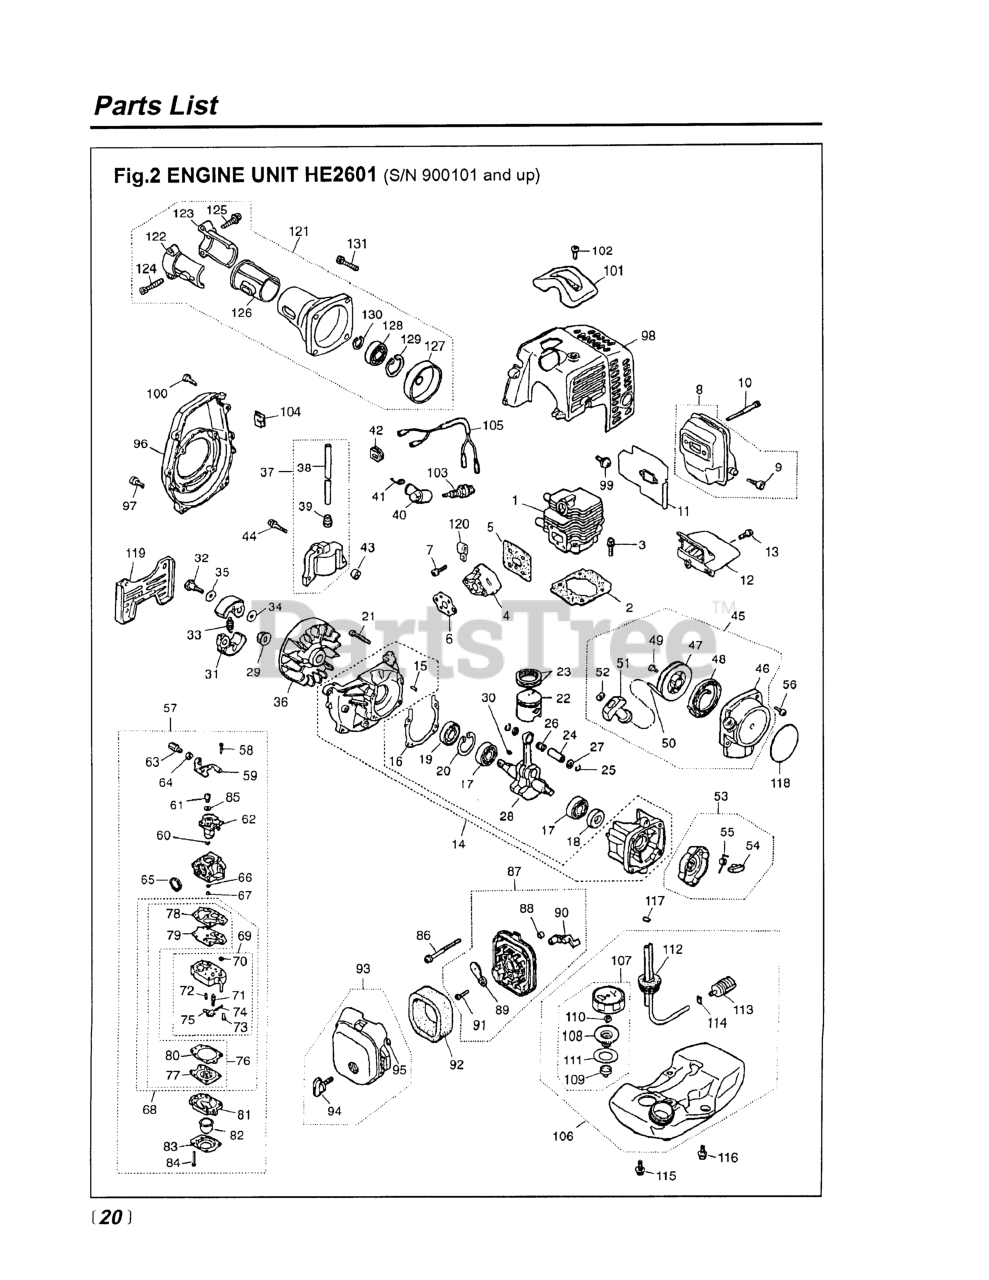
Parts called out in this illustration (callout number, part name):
1	CYLINDER
3	BOLT, M5 X 22
4	INSULATOR (USE -13163)
5	GASKET (RPLS -13120)
6	GASKET (REPLACES -13130)
7	SCREW, M5X20 (RPLS.1400-75510)
8	MUFFLER ASSY (RPLS 5501- )
9	ARRESTER (RPLS 5850-15140)
10	BOLT, M5 x 50
11	GASKET, MUFFLER (RPLS -15111)
13	SCREW, M4 X 16
14	CRANKCASE
15	PIN
16	GASKET (RPLS -21140)
17	BEARING
18	SEAL, OIL (RPLS 1100-21210)
19	SEAL, OIL (RPLS 1140-21220)
20	RING, SNAP, M28 x 1.2
21	BOLT, M5 X 30
22	PISTON
23	RING, PISTON
24	PIN, PISTON
25	RING, SNAP (RPLS 1101-41320)
27	WASHER
28	CRANKSHAFT (RPLS 1850-42000)
30	KEY
31	SHOE (RPLS 1100-51114)
32	BOLT
33	SPRING, CLUTCH (RPLS-51220)
34	WASHER, FLAT (USE 182303)
36	ROTOR
37	COIL ASSY (RPLS 5500-71200)
38	CORD
39	CAP
41	SPRING
42	GROMMET
43	SPACER (RPLS -71260)
44	BOLT
45	RECOIL ASSEMBLY
46	CASE
47	REEL
48	SPRING, SPIRAL
49	SCREW (RPLS -75150)
51	KNOB
52	PLATE, STOPPER
53	PULLEY ASSY (RPLS -75210)
54	RATCHET (RPLS 1850-75220)
55	SPRING, RETURN
56	SCREW, M4 X 16
57	CARBURETOR (WYJ-117)
58	SCREW
60	RING
61	SWIVEL
62	VALVE ASSY
63	SCREW, CABLE ADJUSTER
64	NUT, CABLE ADJUSTER
65	RING, PACKING
66	RING, O
67	JET
69	BODY, PUMP
70	SCREEN
71	VALVE, INLET
73	SCREW
74	PIN
75	LEVER
77	WASHER
78	GASKET, PUMP
79	DIAPHRAGM, PUMP
80	GASKET, DIAPHRAGM
81	BODY, PURGE
82	PUMP, PRIMING
83	COVER, PUMP
84	SCREW
85	WASHER
86	SCREW, M5 X 55
87	BODY-A (RPLS -82101)
88	SLEEVE
89	PLATE, CHOKE (RPLS-82130)
90	LEVER, CHOKE
91	SCREW (REPLACES 50030272)
92	ELEMENT
94	KNOB (RPLS -82220)
95	RING
96	COVER, FAN (RPLS-31110)
97	SCREW, M5X20 (RPLS.1400-75510)
98	COVER, ENGINE (RPLS -32111)
99	SCREW, M5 x 12
100	SCREW, HOUSING
101	GUARD, PLUG
102	SCREW,M5 X 14 (RPLS 1400-15510
105	CORD COMPLETE
109	HOLDER, CAP
110	VALVE (NLA WHEN OUT)
111	PACKING
112	PIPE COMPLETE
113	FILTER (RPLS 1850-85300)
114	CLIP (REPLACES 2841-31280)
115	SCREW
116	SCREW W/ WASHER
117	CLIP
118	LABEL, RECOIL (HE2601S)
119	STAND
120	CLAMP
122	BRACKET (A) (RPLS -31210)
123	BRACKET (B) (REPLACES -31220)
124	BOLT, M5 X 30
126	CUSHION
128	BEARING
129	RING, SNAP, M28 x 1.2
130	RING, SNAP (RPLS 3130-13270)
131	BOLT, M6 x 20
